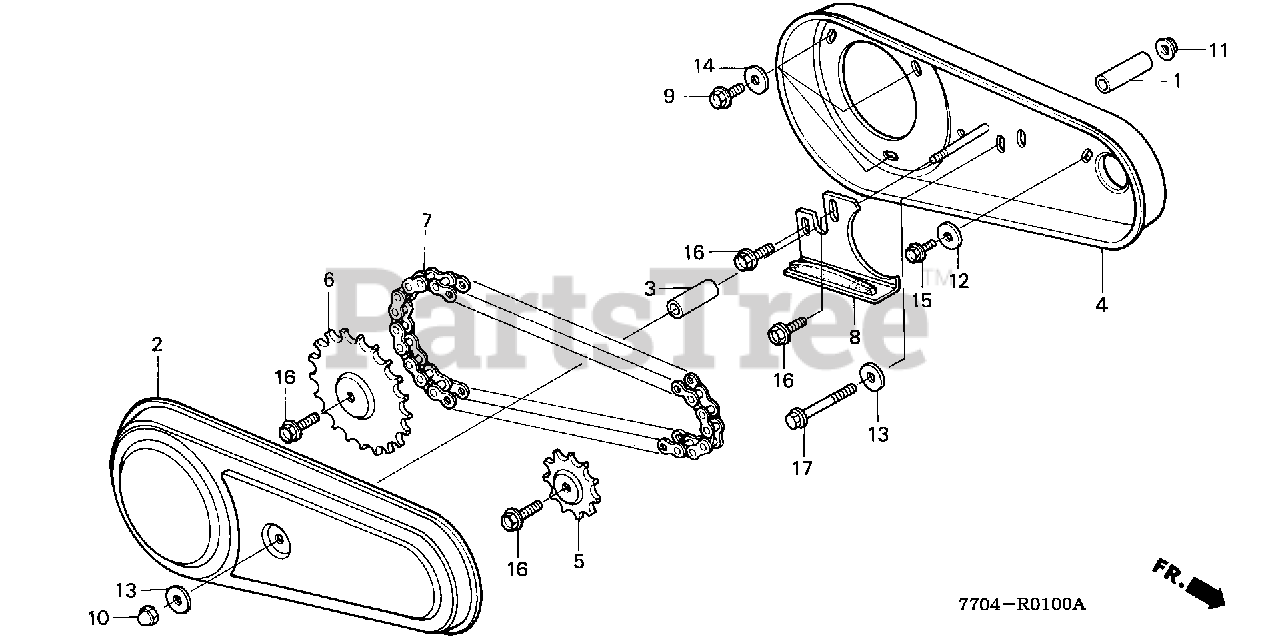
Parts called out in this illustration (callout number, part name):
1	COLLAR, FR. ENGINE HANGER (A)
2	COVER, PRIMARY
3	COLLAR, DISTANCE
4	CASE, PRIMARY *R280* (POWER RED)
5	SPROCKET, PRIMARY DRIVE (10T)
6	SPROCKET, PRIMARY DRIVEN (23T)
7	CHAIN, PRIMARY
8	TENSIONER, PRIMARY CHAIN
9	BOLT, FLANGE (8MM)
10	NUT, CAP (8MM)
11	NUT, FLANGE (8MM)
12	WASHER, PLAIN (6MM)
13	WASHER, PLAIN (8MM)
14	WASHER, PLAIN (8MM)
15	BOLT, FLANGE (6X12)
16	BOLT, FLANGE (8X16)
17	BOLT, FLANGE (8X30)
